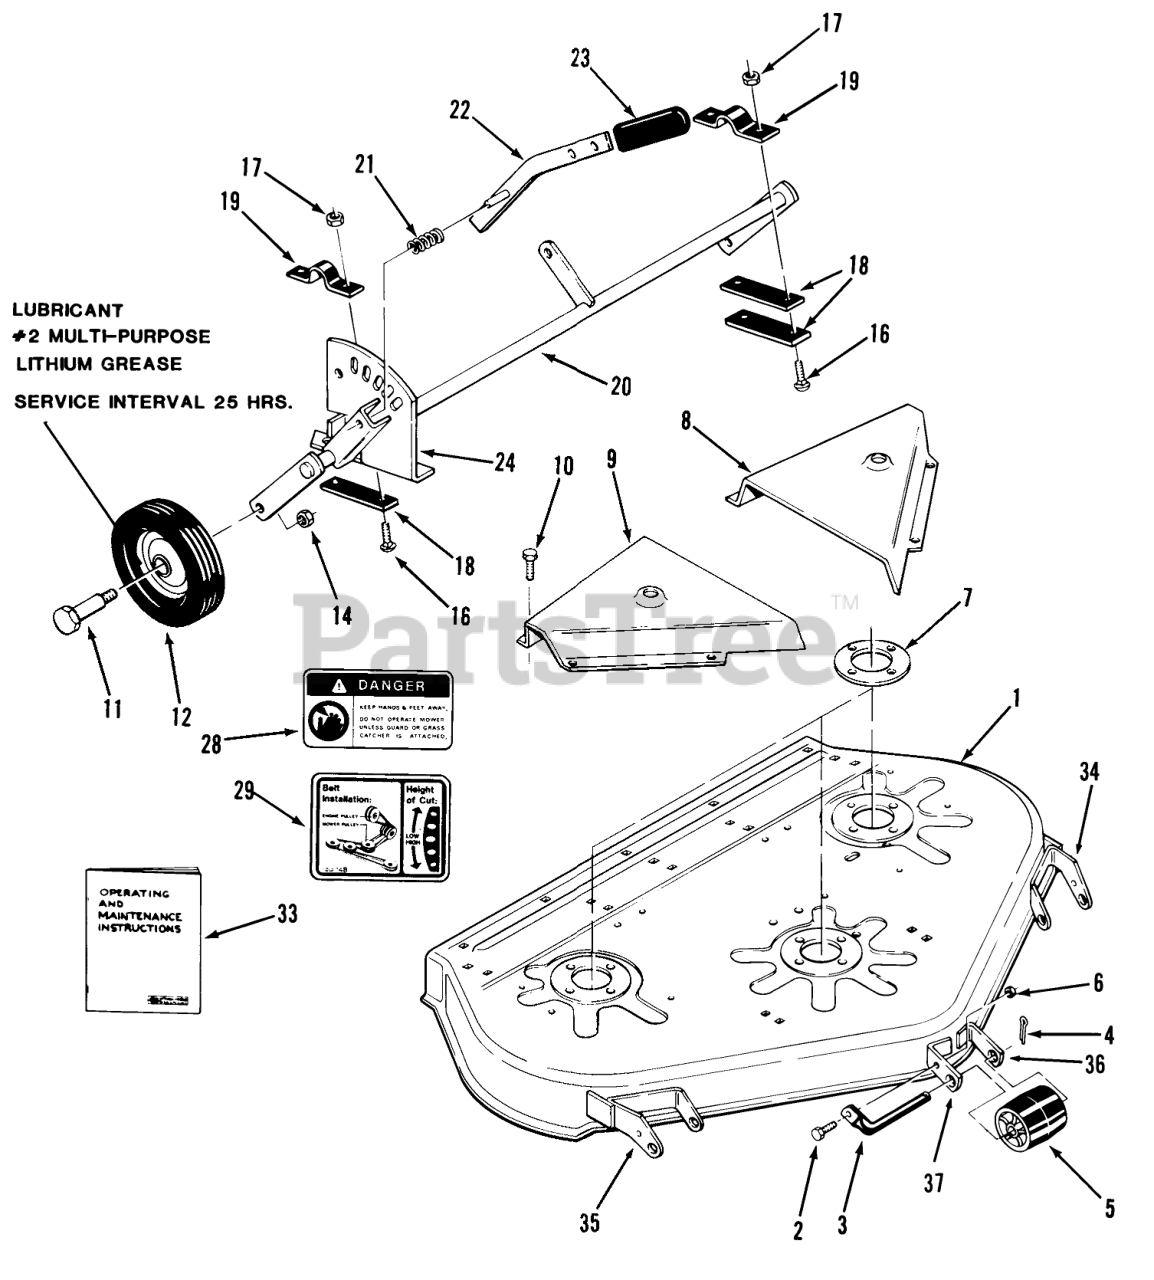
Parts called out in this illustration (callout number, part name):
1	Mower Deck
2	Bolt
3	ROLLER-SHAFT
4	Cotter Pin
5	Roller
6	Nut
7	PLATE-SPINDLE
8	Belt Cover LH
9	Belt Cover RH
10	Bolt
11	BOLT-SHOULDER
12	WHEEL
14	Nut
16	Bolt
17	NUT
18	Bar
20	Gage Wheel Support
21	SPRING-COMPRESSION
22	Lever
24	Quadrant
28	Danger Decal
29	DECAL-HEIGHT & BELT
33	Operating and Maintenance Instruction
34	BRKT-ROLER R
35	BRKT-ROLLER R
36	LH Center Roller Support (part of item 1)
37	RH Center Roller Support (part of item 1)
